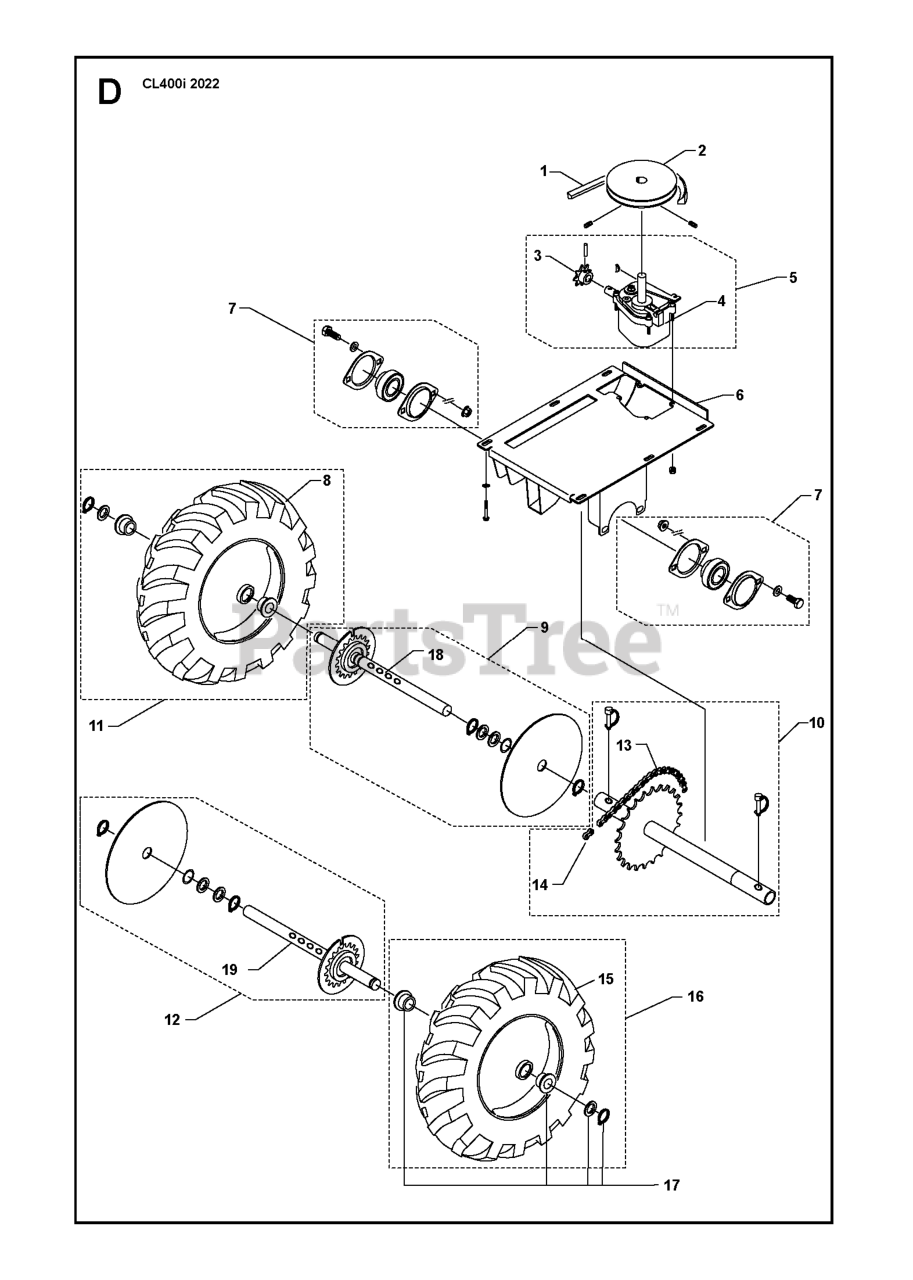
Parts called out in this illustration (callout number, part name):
4	Transmissions
7	Ball Bearings
13	Chain Catcher
17	BUSHNG KIT
18	Axles
19	Axles
